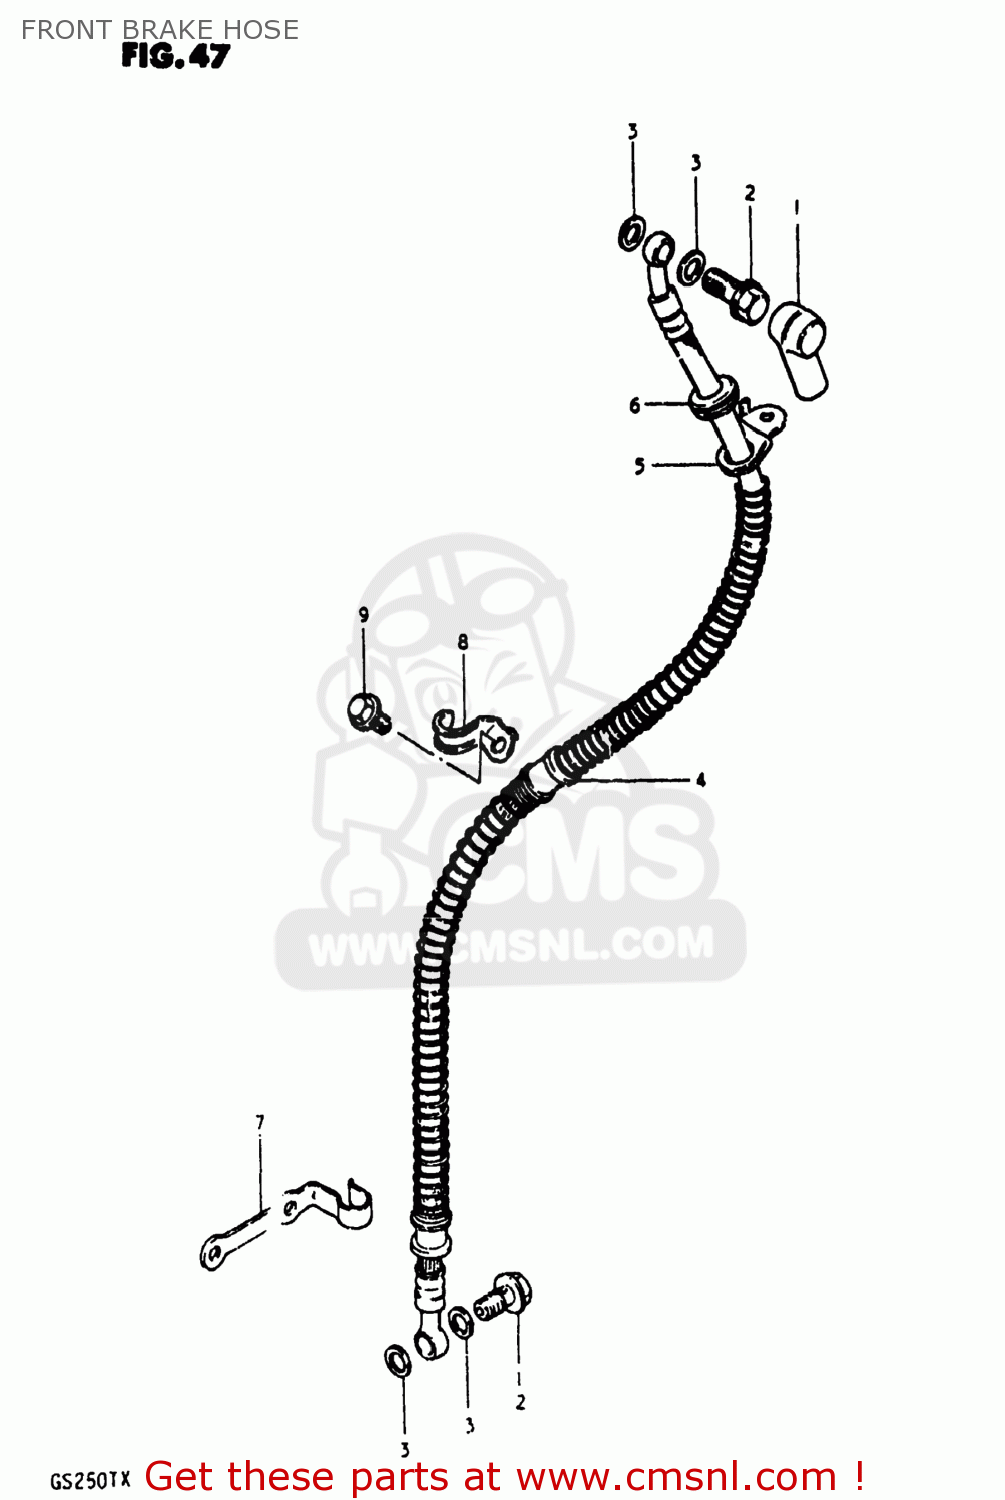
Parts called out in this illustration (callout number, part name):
1	BOOT,MASTER CYLINDER
2	BOLT,UNION
3	WASHER
4	HOSE,FRONT BRAKE
5	GUIDE,BRAKE HOSE
6	GROMMET
7	GUIDE,BRAKE HOSE NO.2
8	GUIDE,BRAKE HOSE NO.3
9	BOLT
